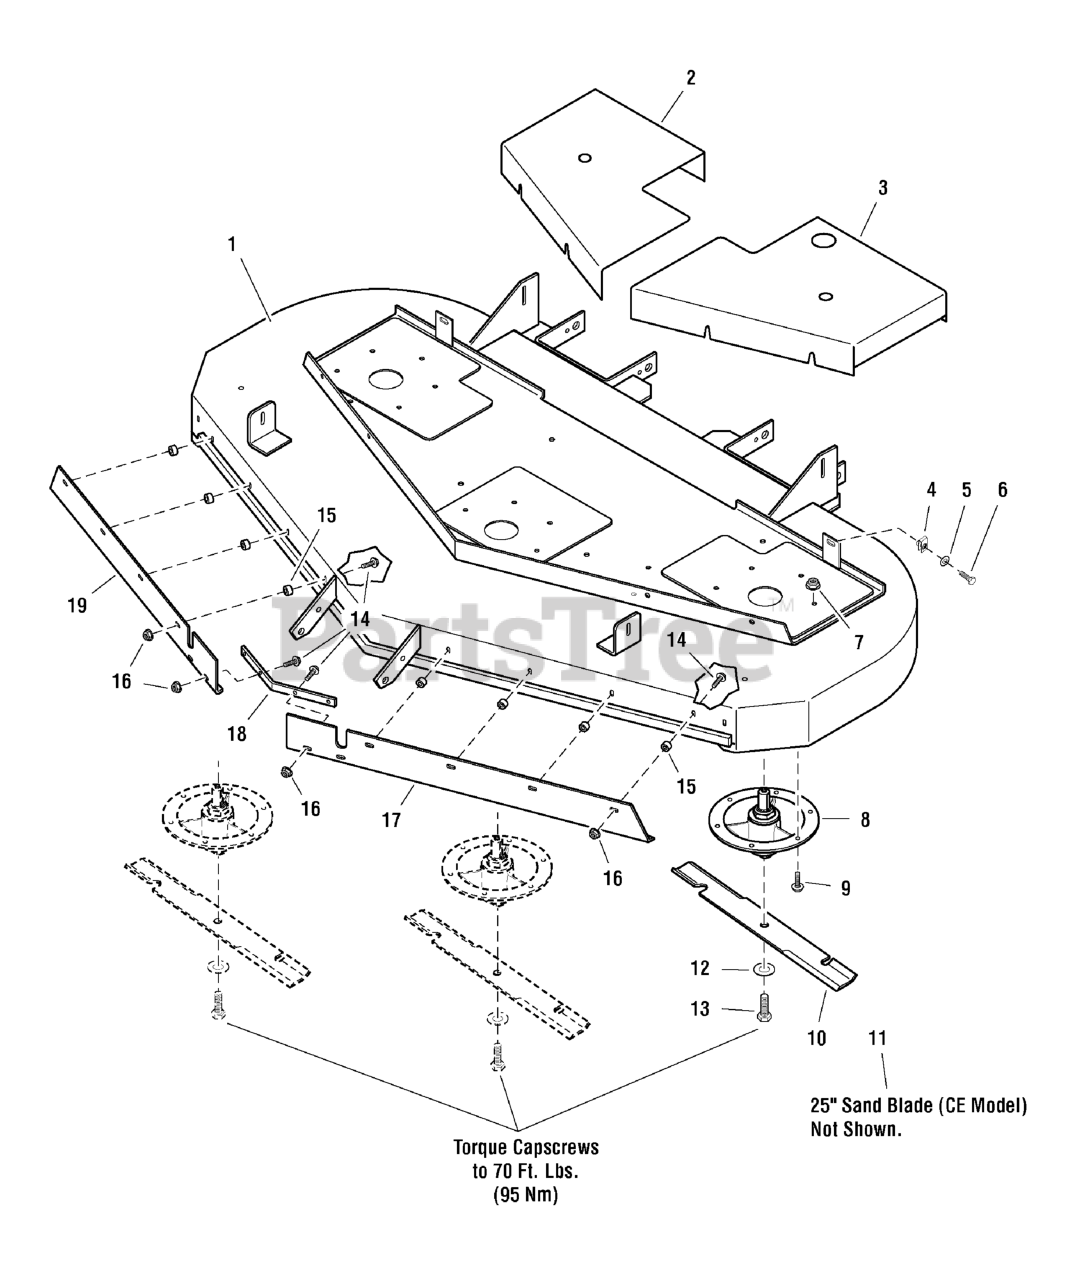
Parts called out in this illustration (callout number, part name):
1	DECK SHELL W/DECALS, 72 RD
2	SPINDLE COVER - RH
3	SPINDLE COVER - LH
4	BODY CLIP, 5/16-18-7GA MATERIAL
5	WASHER, 5/16" SAE
6	BOLT, 5/16-18 X 3/4 GD5
7	NUT, 3/8-16 Hex Nylock Flange
8	SPINDLE ASSEMBLY
9	BOLT, Flange Head, 3/8-16 x 1-1/4
10	BLADE, 25" (SET OF THREE)
11	MOWER BLADE, SAND, 25"
12	WASHER, 5/8" GRADE 8, YZ
13	BOLT, 5/8-11 X 1-3/4 GD8
14	BOLT, Flange Head, 5/16-18 x 1-1/4
15	SPACER, .39 X .75 X .50, CZ
16	NUT, 5/16-18 Hex Nylock Flange
17	BLOWOUT BAFFLE - LH
18	BAFFLE, REINFORCEMENT - BLK
19	BLOWOUT BAFFLE - RH
